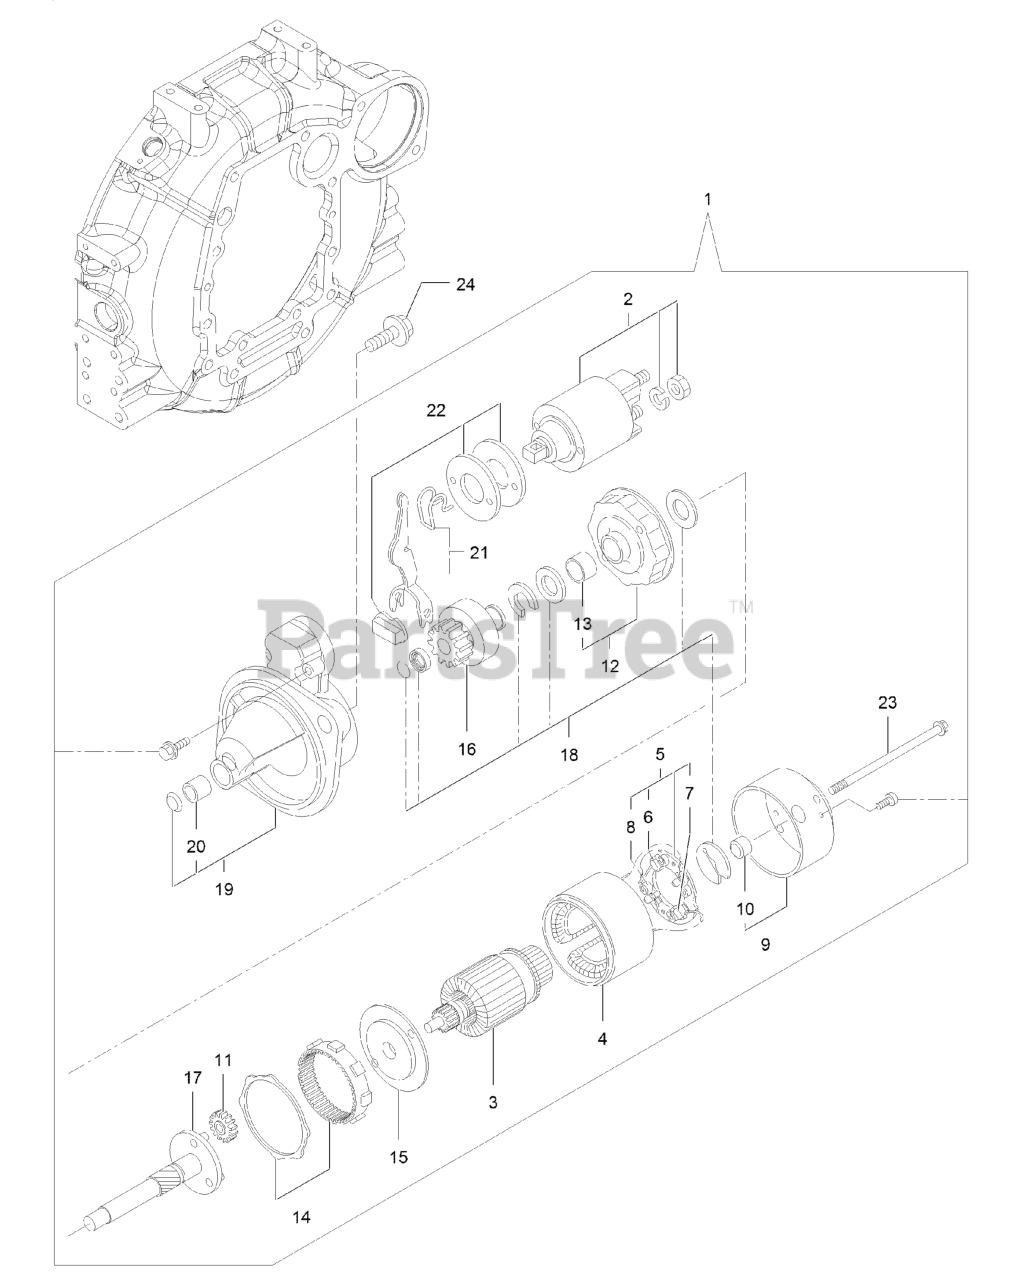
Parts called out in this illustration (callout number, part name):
1	STARTER ASM
2	SWITCH ASM
3	Armature ASM
4	Yoke ASM
5	Brush Holder ASM
7	BRUSH SET
9	Cover ASM
12	Bracket
13	Bracket
15	Bracket
16	PINION ASM
18	Washer Set
19	Case ASM
20	Metal-Starter
21	Lever Set
22	Dust Cover ASM
23	BOLT-THROUGH
